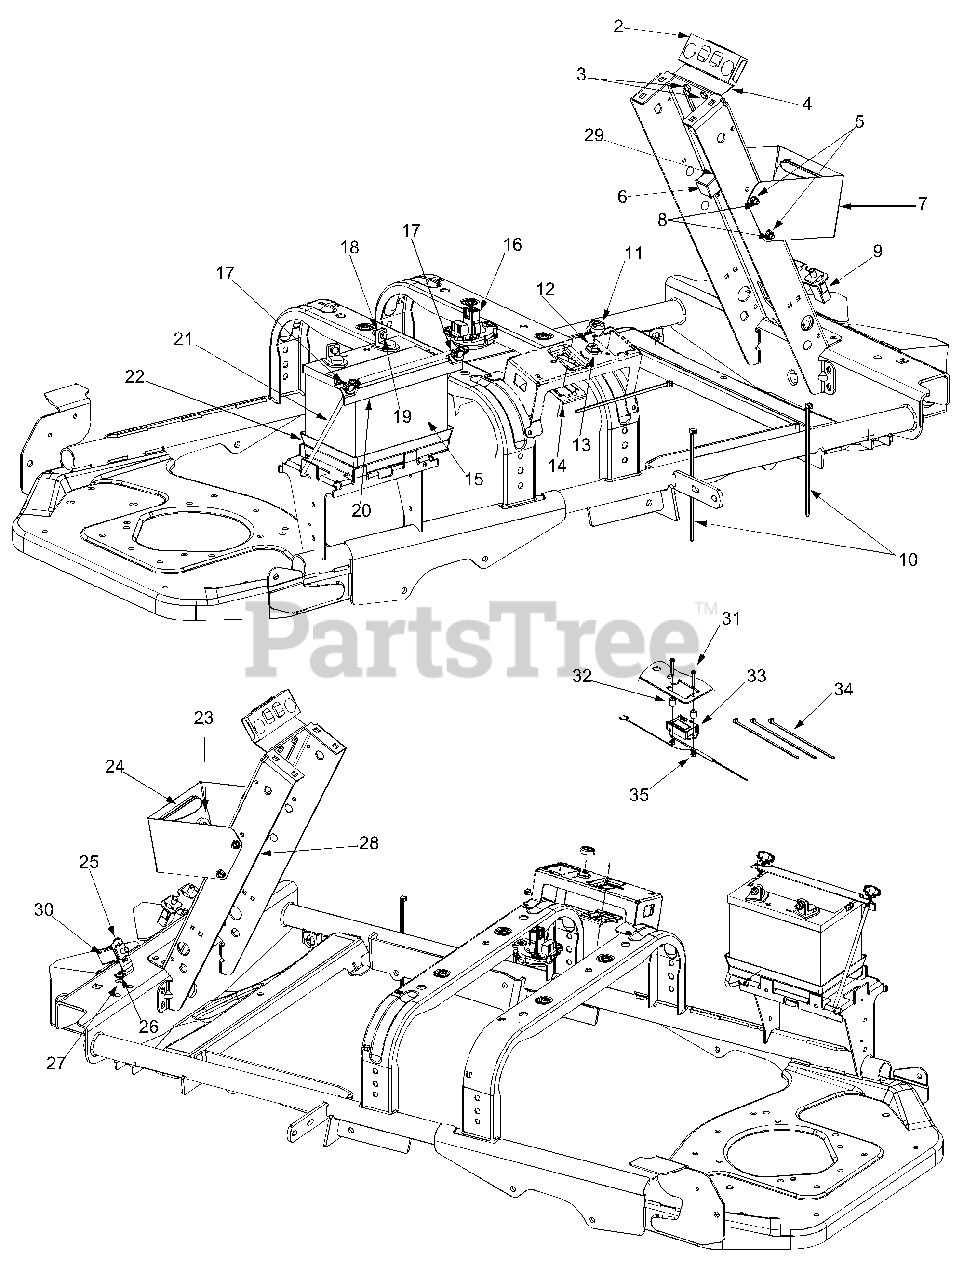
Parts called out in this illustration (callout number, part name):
2	Foam Protector, Indicator Light
3	Hex Cap Screw 1/4-20 x .50
6	Relay
9	Switch, Plunger Safety
10	Cable Tie
11	Cap, Ignition Switch
12	Nut, Ignition Switch, 5/8-32
13	Switch, Ignition
14	Bracket, PTO Switch Retainer
16	Switch, Seat
17	Nut, Nylon Wing, 1/4-20
18	Nut, Hex Sems, 1/4-20
19	Screw, Hex Cap, 1/4-20 x .75 GR5
20	Strip, Battery Retainer
21	Rod, Battery Retainer
22	Tray, Battery
23	Headlight Assembly
24	Bezel, Headlight
25	Spring, Switch Mounting
26	Screw, Machine, #10-24 x 5/8
27	Nut, Hex Insert Lock, #10-24
28	Voltage Sensor
29	Ratchet Retainer
30	Switch, Plunger Safety
31	Machine Screw #10-24
32	Spacer .315 ID x .50 OD
33	Hour Meter
34	Cable Tie
35	Lock Nut #10-24
